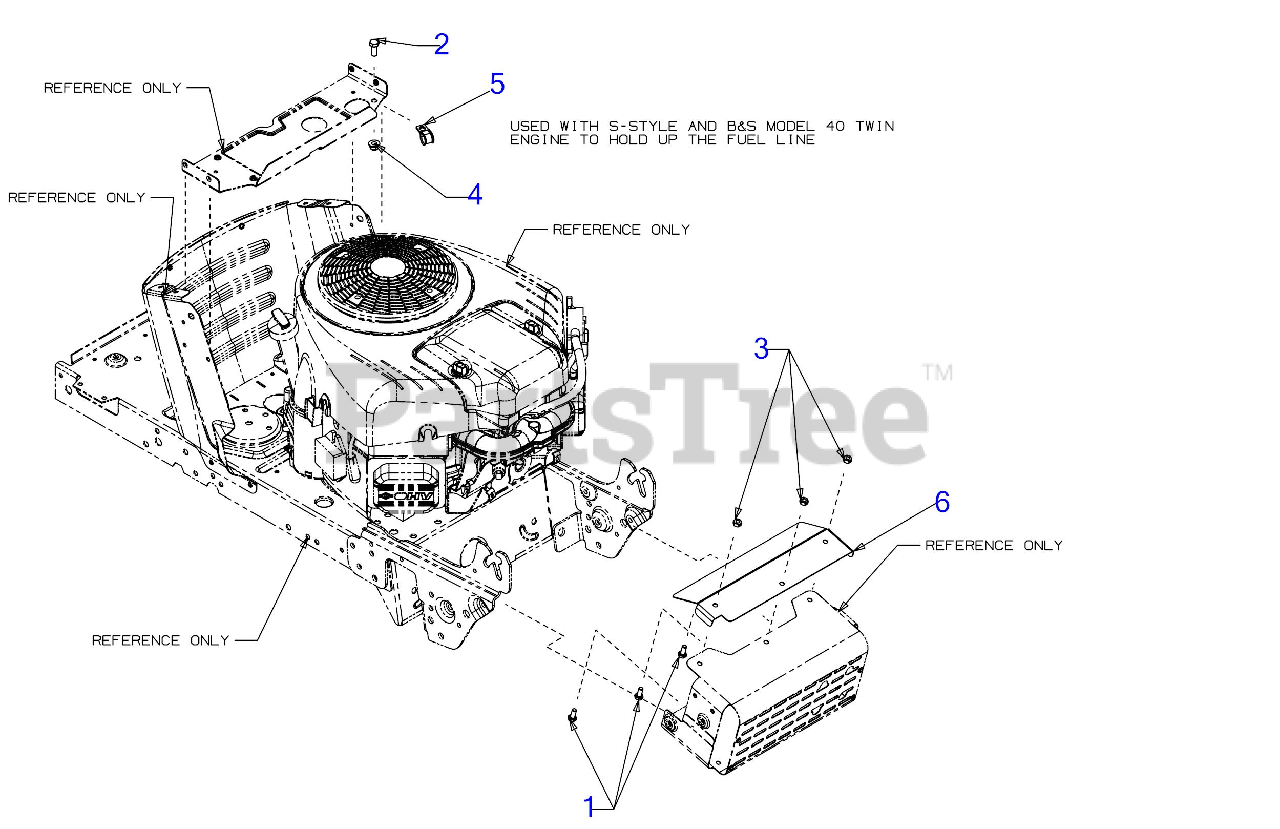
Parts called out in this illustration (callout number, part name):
1	SCREW 1/4-20 x .620 GR5
2	SCREW 5/16-18 x .75 GR5
3	HEX NUT
4	FLANGE LOCK NUT 5/16-18
6	MUFFLER SHIELD EXTENSION
